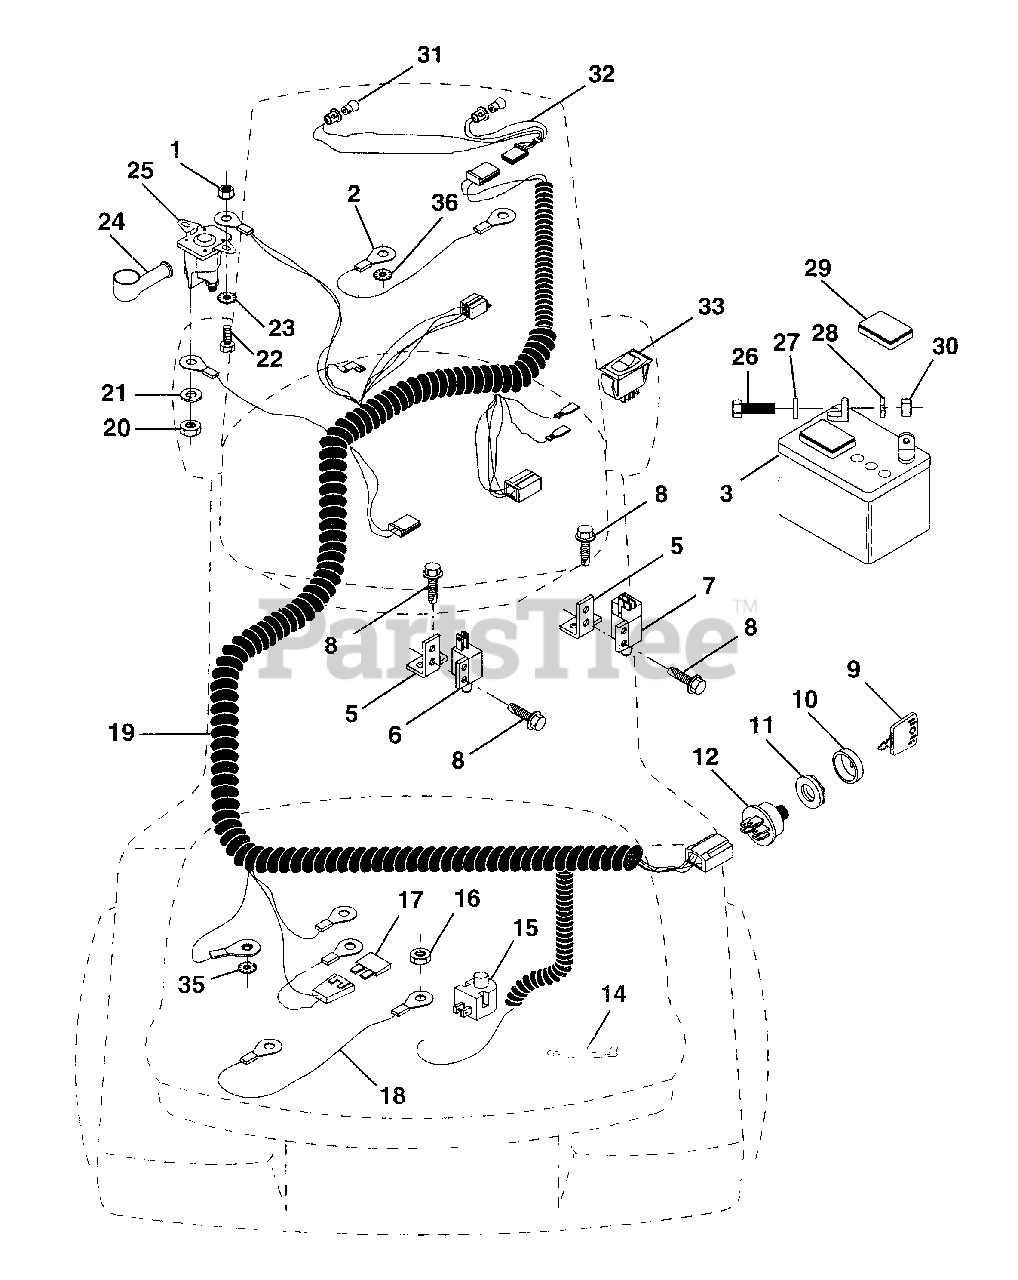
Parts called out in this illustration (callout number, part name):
1	Nut, Hex, Keps 1/4-20
2	Assembly, Cable
3	Battery
5	Bracket, Switch
6	Switch, Interlock, 2 Terminal
7	Switch, Interlock, 4 Terminal
8	Screw, Hex Head, Self-Tapping # 10-24 x 1/2
9	Key, Molded
10	Cover, Ignition Key
11	Nut, Ignition
12	Switch, Ignition
14	Tie, Cable
15	Switch, Plunger
16	Nut, Hex, Keps 5/16-18
18	Assembly, Cable
19	Harness, Ignition
20	Nut, Hex, Jam 1/4-20
21	Washer, Lock 1/4
22	Bolt, Hex Head, Fin. 1/4-20 UNC x 1/2 Grade 5
23	Washer, Lock, External Tooth 1/4
24	Cover, Terminal
25	Solenoid
26	Bolt, Hex Head 1/4-20 UNC x 3/4
27	Washer 9/32 x 5/8 x 16
28	Washer, Lock 1/4
29	Cap, Battery
30	Nut, Hex, Fin. 1/4-20 UNC
31	Harness, Headlight
32	Bulb, Light
33	Switch, Light
35	Washer, Lock, External Tooth 3/8
36	Washer, Lock, Internal Tooth 1/4
